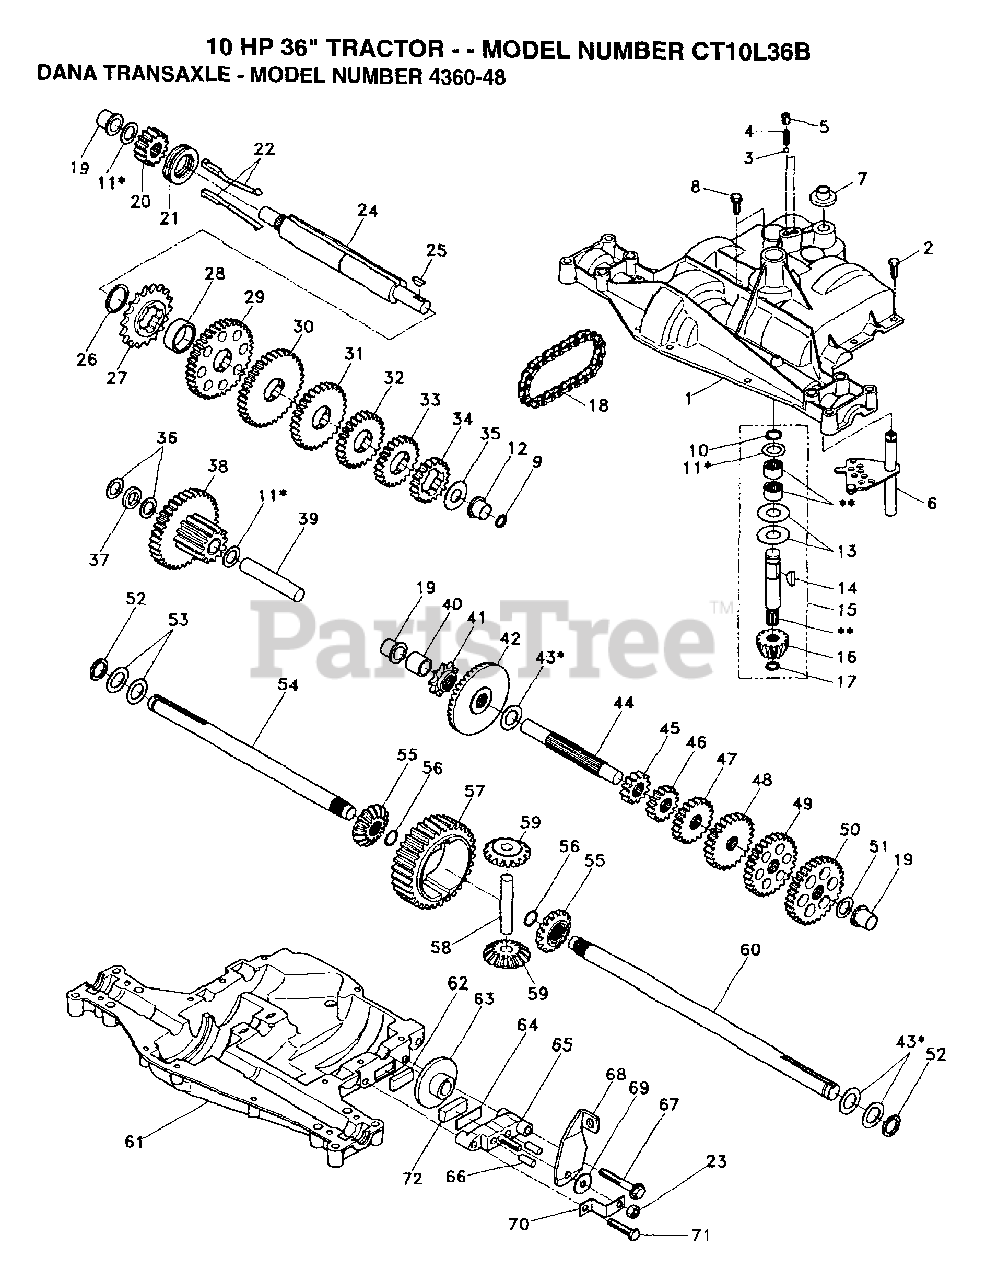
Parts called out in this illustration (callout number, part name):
4	"SPRING, DETENT LT"
5	"SCREW, SET LT"
6	KIT SHIFTER ASM
7	SHIFTER BOOT
8	SCREW TAP W/SEAL
9	SQUARE RING
10	RETAINING RING LT
11	ASM KIT SHIM 4689
12	"FLANGE, BEARING"
13	WASHER T
14	WOODRUFF KEY
15	AS KIT INPUT SHFT
16	PINION 14T T
17	"RING,RETAINING LT"
18	"CHAIN,24 PTCH LT"
19	BEARING.FLNG.5510
20	GEAR SPUR 14T
21	COLLAR CLUTCH
22	ASM KIT CLTCH KEY
23	NUT.LOCK.5/16-24
24	SHAFT INTERM
25	WOODRUFF KEY
26	"RING,RETAINING LT"
27	SPROCKET 18T T
28	SPACER YT
29	KIT.GEAR.12/37TH
32	GEAR 25T LT
33	GEAR SPUR 22 TT
34	SPUR GEAR 19T
35	"WASHER, PLAIN LT"
36	WASHER 025
37	SPACER
38	ASSM GEAR COMB
39	SHAFT IDLER
40	SPACER T
41	SPROCKET 9T LT
43	ASM KIT SHIM
44	SHAFT T
48	"GEAR, SPUR 25T LT"
49	GEAR 28T T
50	"GEAR, SPUR 31T LT"
51	WASHER 060
52	NEOPRENE WASHER
53	WASHER 031
55	GEAR 15T T
56	"RING,RETAINING LT"
58	SHAFT T
59	GEAR, MITER, 15 TEETH
62	PUCK T
63	BRAKE DISC. T
64	SPACER LT
66	PIN T
69	WASHER LT
71	"SCREW, TAPPING LT"
72	PUCK T
